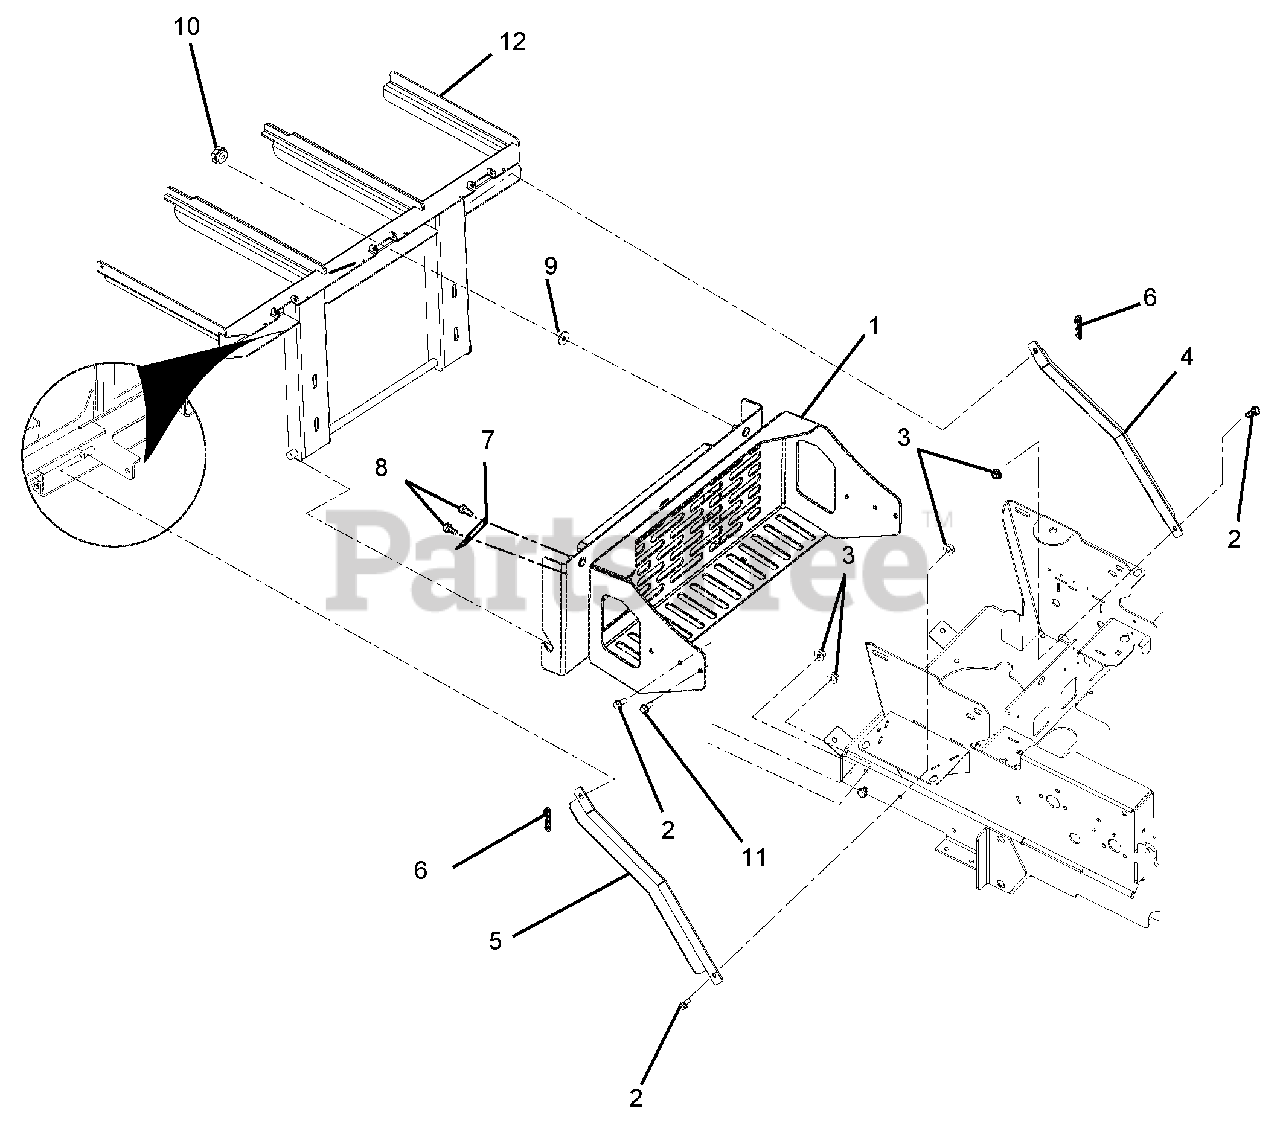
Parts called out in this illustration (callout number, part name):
1	Weldment, 100i Bagger Mount
2	Bolt, Hex .38-16 x 2.50 Grade 5
3	Nut, .38-16 Nyloc Flange
4	Weldment, Left Bagger Support
5	Weldment, Right Bagger Support
6	Pin, Hair #25
7	Shield, Heat Deflection
8	Screw, Tapping .38-16 x 0.50
9	Washer, Flat Steel .563 x 1.38 x .105
10	Knob, Clamping .312-18 Nyloc
11	Bolt, Round Head Square Neck .38-16 x 2.50 Grade 5
12	Weldment, XL Bagger Frame
